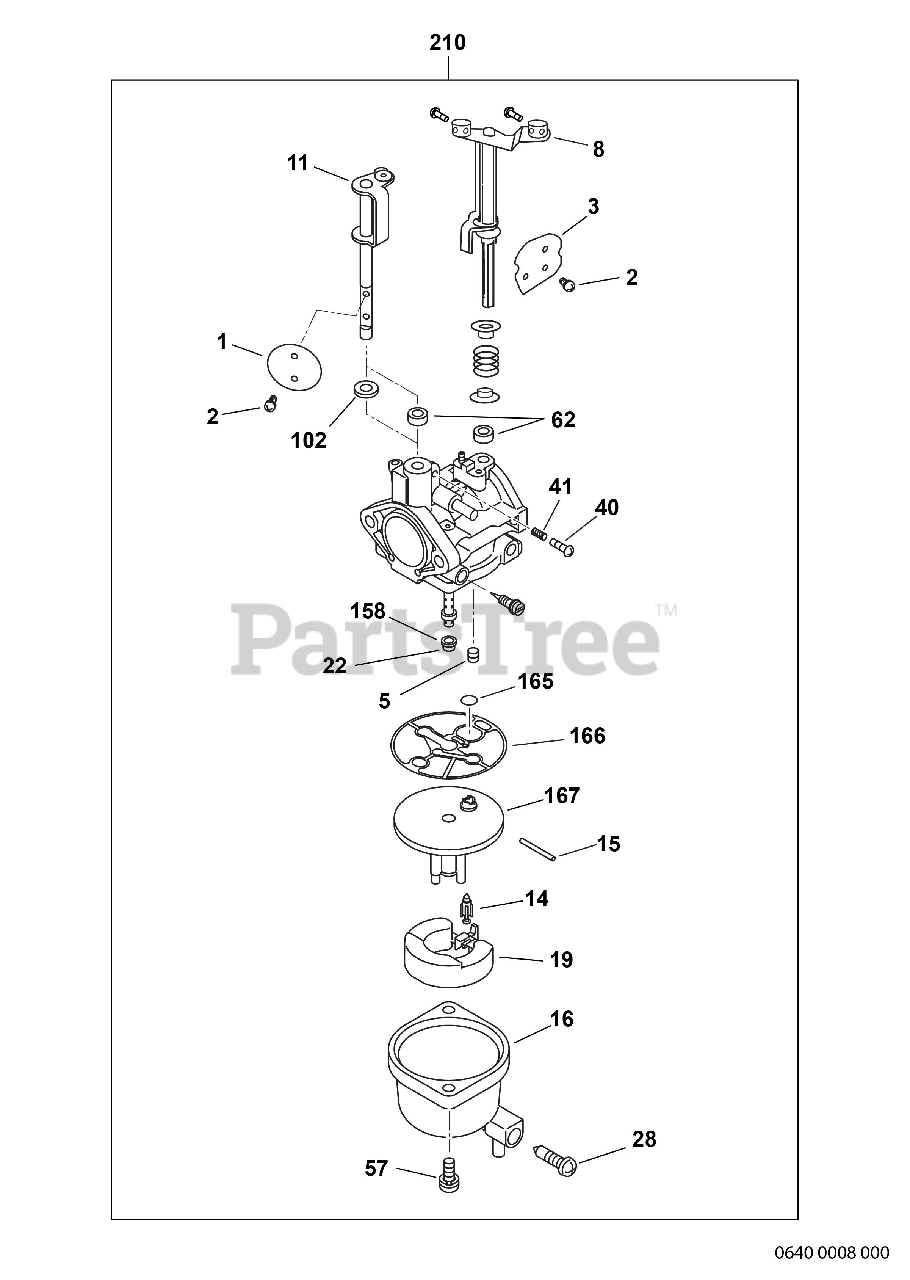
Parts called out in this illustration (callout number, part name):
1	VALVE, THROTTLE
2	SCREW, VALVE SET
11	SHAFT AY, THROTTLE
14	VALVE AY FLOAT
16	CHAMBER CP, FLOAT
40	SCREW, THROTTLE ADJUST
41	SPRING, THROTTLE ADJUST
62	FILTER, CHOKE SHAFT
